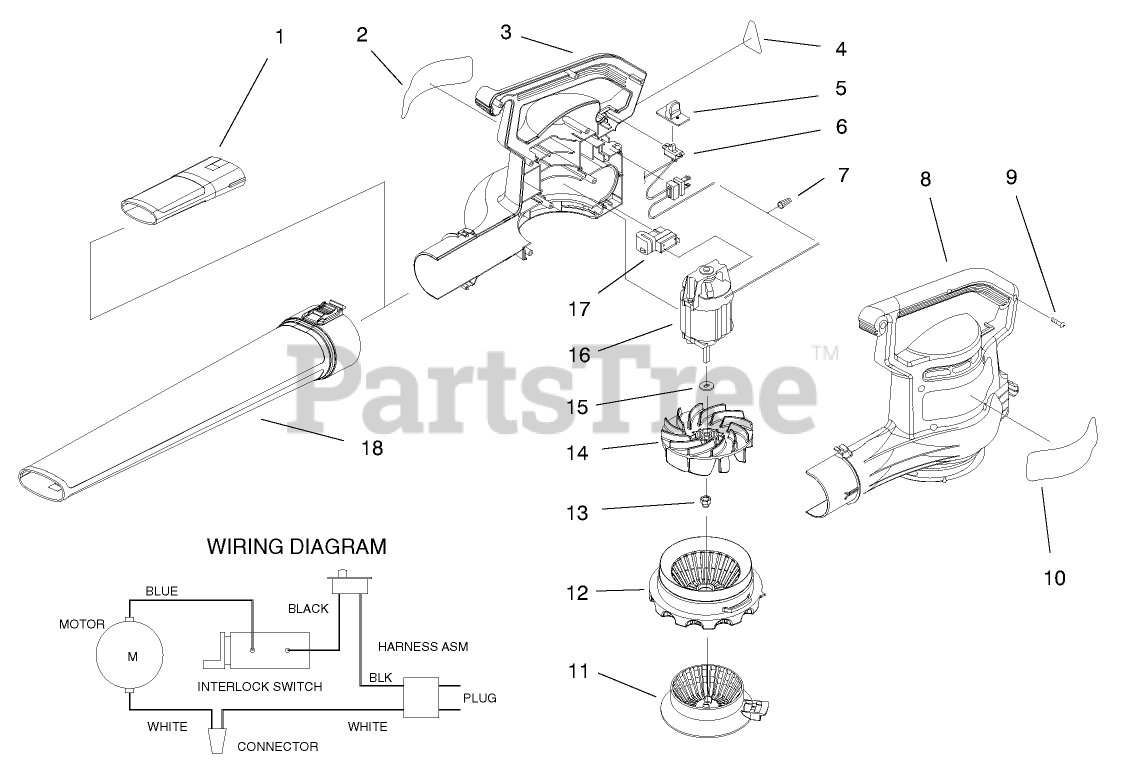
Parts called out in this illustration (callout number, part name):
1	INSERT - TUBE
2	DECAL, LOGO, SUPRBLWR
3	HOUSING, RH (BLACK)
4	DECAL - INFORMATION
5	COVER - SWITCH, RED
6	HARNESS ASSEMBLY
7	CONNECTOR-NUT, WIRE
8	HOUSING, LH (BLACK)
9	SCREW-PPH
10	LABEL STOCK-BLOWERS
11	CHOKE - AIR, RED
12	Cover-Inlet
13	NUT-HEX
14	IMPELLER - BLOWER
15	WASHER
16	MOTOR - ELECTRIC, 120 V
17	SWITCH, INTERLOCK
18	TUBE-BLOWER LONG
